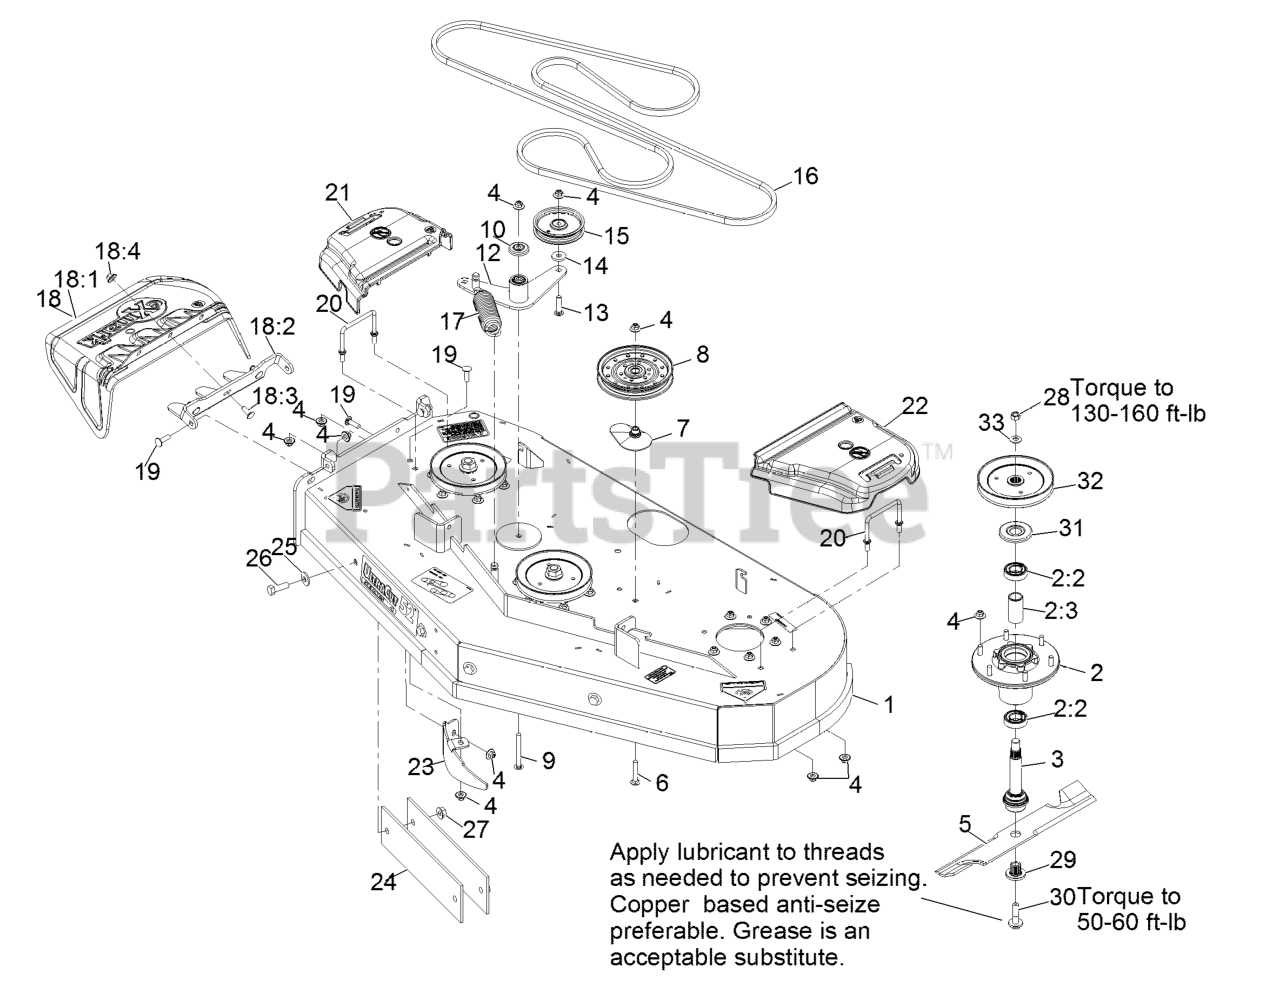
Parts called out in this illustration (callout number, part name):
1	DECK ASM-524
2	ASM-CUTTER HSG WITH BEARINGS
2:2	BEARING-BALL
2:3	SPACER-BEARING
3	ASM-SPINDLE AND SEAL
4	Nut-Nyloc 3/8-16 Flg
6	Bolt-Carriage 3/8-16 X 2 1/4
7	SPACER-PULLEY
9	SCREW-CARR
10	GUARD-TOP
12	IDLER ARM ASM W/BEARINGS
13	SCREW-CARR SPECIAL
15	PULLEY-IDLER
16	BELT-V
17	SPRING-EXTENSION
18	ASM,DISCHARGE CHUTE
18:1	CHUTE,DISCHARGE
18:2	BRACKET,DISCHARGE CHUTE
18:3	SCREW-CARR
18:4	Nut-Nyloc 3/8-16 Flg
19	Bolt-Carriage 3/8-16 X 1 1/4
20	WIREFORM-COVER
21	COVER-BELT, RH
22	COVER-BELT, LH
23	BAFFLE-DOGLEG, LZ-VT52
24	BAR,WEIGHT
25	WASHER-SPRING
26	SCREW-HH
27	NUT-HHF
28	NUT-HEX
29	BUSHING,SPLINED
30	SCREW,SEMS 1/2-20 X 2.19
31	GUARD,BEARING TOP .989
32	SHEAVE,BLADE DRIVE 6.50
